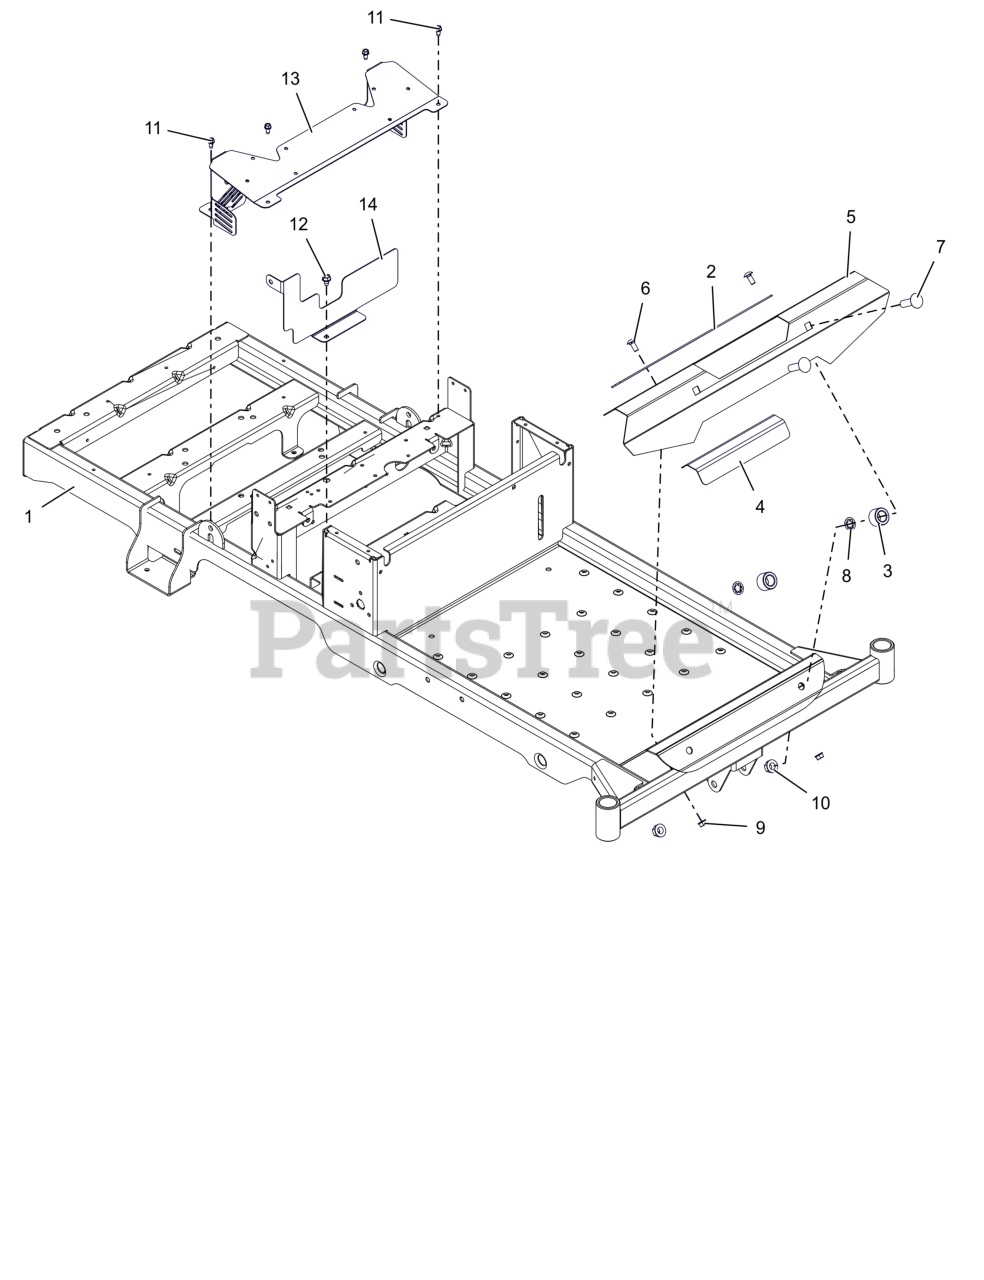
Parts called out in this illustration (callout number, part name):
1	KIT- EDGE FRAME W/DECALS
2	GRIP, ADHESIVE (1" X 16" BLK)
3	TUBE, UPPER CONTROL PIVOT
4	GRIP, STEP
5	FOOTREST, (ORANGE)
6	BLT, RHSSN.31-18X.750 G5 ZCC
7	BLT,RHSN .50-13X1.75 G5 ZCC
8	NUT-PUSH, .50
9	NUT,LK-CTR-FLG .31-18 GF ZCC
10	NUT-LK-CTR-FLG .500-13 GG ZCC
11	SCR-TAP .25-20X.50 HWH ZCC
12	SCR,TAP .312-18X.50 HWH TR ZCC
13	PLATE, FAN GUARD,CE
14	MUFFLER, LONCIN 635CC
